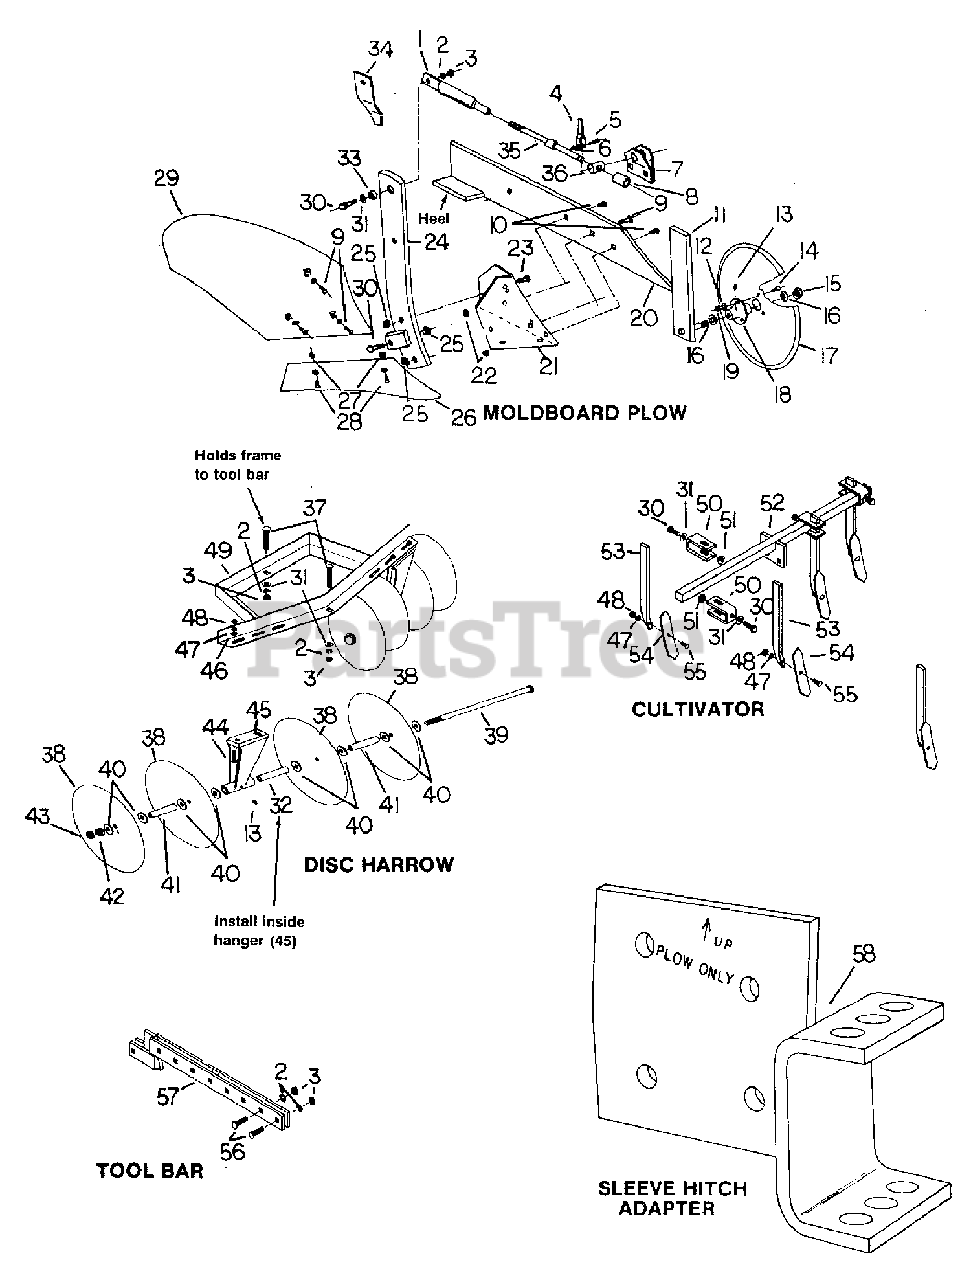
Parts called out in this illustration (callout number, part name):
1	TREAHDED TUBE
2	LOCKWASHER, 1/2
3	NUT, Hex, 1/2
4	HANDLE ASSEMBLY
5	BOLT, Hex, 1/4 x 1-1/4
6	NUT, 1/4" Hex Lock
7	BRACKET ASSEMBLY
8	SPACER, Tube
9	BOLT, Plow, 1/2 x 2
10	BOLT, Plow, 3/8 x 1
11	COULTER HANGER ASSEMBLY
12	WASHER, Plain, 5/16
13	FITTING, Lube
14	BOLT, Carriage, 5/16-3/4
15	NUT, Hex, Lock, 5/8
16	WASHER, Plain, 5/8 SAE
17	BLADE, Coulter
18	HUB, Coulter
19	NUT, 5/16" Hex Lock
20	LANDSIDE ASSEMBLY
21	PLOW FROG
22	NUT, Square, 3/8
23	BOLT, Carriage, 1/2 x 1-1/2
24	STANDARD ASSEMBLY
25	NUT, Square, 1/2
26	10" SHARE
27	NUT, Square, 7/16
28	BOLT, Plow, 7/16-1
29	MOLDBOARD, 10"
30	BOLT, Hex, 1/2 x 1-1/2
31	WASHER, Plain, 1/2
34	BRACKET, Plow
35	CRANK ASSEMBLY
37	BOLT, Carriage, 1/2-3-1/2
38	BLADE, Disk
39	BOLT, Gang, 3/4-16
40	WASHER, Flat, 3/4
42	NUT, Hex, 3/4
43	NUT, Hex, Jam, 3/4
44	BOLT, Carriage, 3/8 x 1-1/2
45	HANGER, Bearing
46	WASHER, Plain, 3/8
47	LOCKWASHER, 3/8
48	NUT, Hex, 3/8
49	FRAME ASSEMBLY
51	NUT, Flange, 1/2
52	CROSS BAR ASSEMBLY, 36"
55	BOLT, Plow, 3/8-1-1/2
56	BOLT, Carriage, 1/2 x 2
57	DRAWBAR ASSEMBLY
58	BRACKET ASSEMBLY, Hitch
